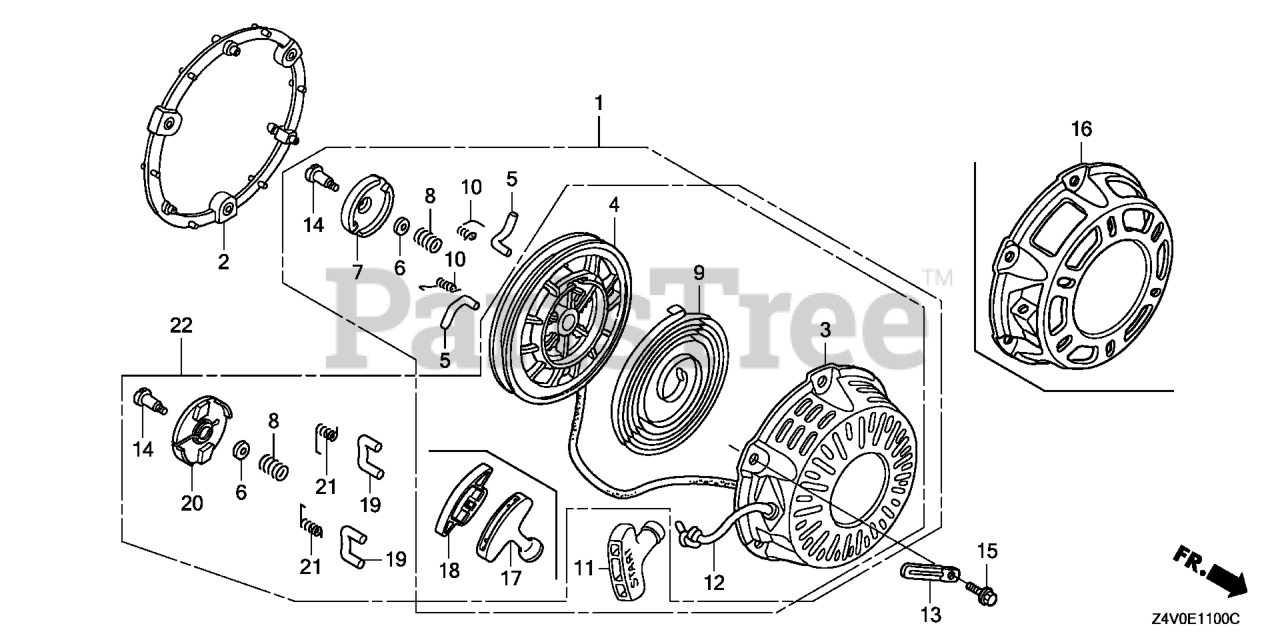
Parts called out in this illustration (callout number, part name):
2	SPACER, RECOIL STARTER MOUNTING *NH1* (BLACK)
2	SPACER, RECOIL STARTER MOUNTING *R280* (POWER RED)
3	CASE, RECOIL STARTER *R280* (POWER RED)
3	CASE, RECOIL STARTER *NH1* (BLACK)
4	REEL, RECOIL STARTER (BLACK)
6	PLATE, FRICTION
8	SPRING, FRICTION
9	SPRING, RECOIL STARTER
12	ROPE, RECOIL STARTER (#5X55")
13	CLIP, SUB-WIRE
14	SCREW, SETTING
15	BOLT, FLANGE (6X18)
17	KNOB, RECOIL STARTER
18	KNOB, REINFORCEMENT
19	RATCHET, STARTER
20	GUIDE, RATCHET
21	SPRING, RETURN
22	STARTER ASSY., RECOIL *R280* (COO)(FOR U.S.A.) (POWER RED)
22	STARTER ASSY., RECOIL *NH1* (BLACK)
